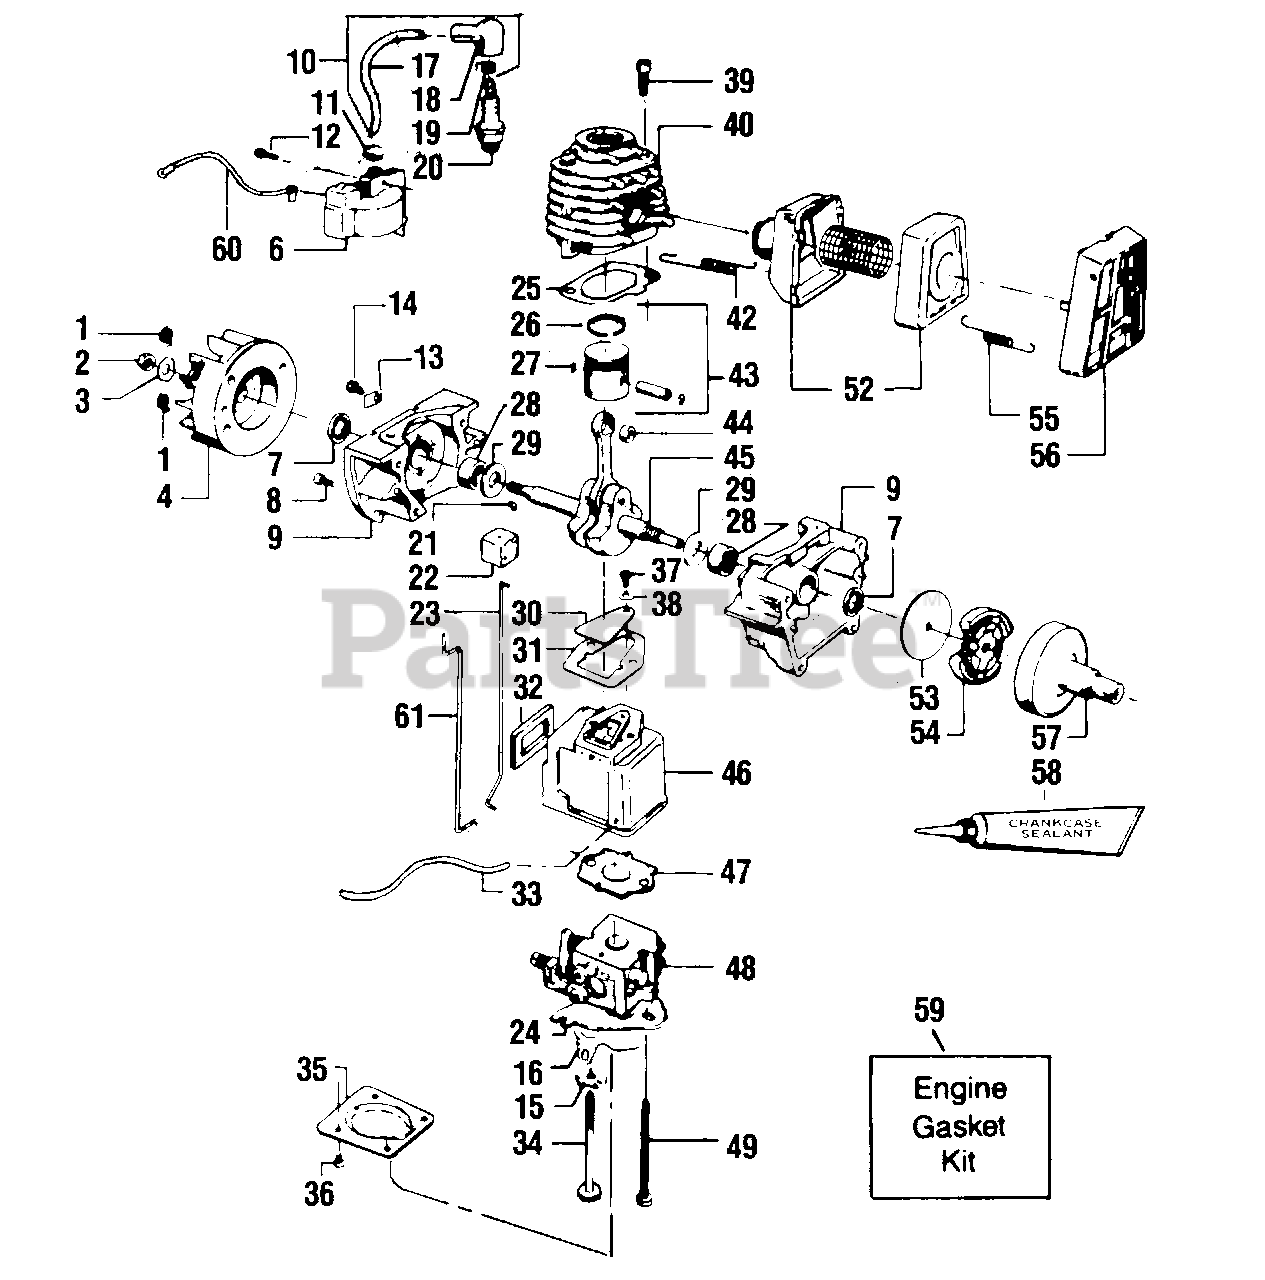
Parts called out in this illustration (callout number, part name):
1	Starter Dog Spring
2	Flywheel-Nut
3	Flywheel Washer
4	Flywheel Assembly
6	Ignition Module Kit
7	Crankcase Seal
8	Screw-Crankcase
9	Crankcase Assembly
10	High Tension-Load Assembly Incl. #17, 18 & 19
11	Grommet-Plug Wire
12	Screw #8-32x3/4"- Fil. Hd.-Ignition Module
13	Choke Wire Clamp
16	Choke Shutter
17	High Tension Lead Wire
18	Spark Plug Boot
19	Spark Plug Lead Connector
20	Spark Plug (CJ-14)
21	Key-Flywheel
22	Boot-Throttle Choke Wire
23	Throttle Wire (Red)
24	Guide Plate
25	Cylinder Gasket
26	Ring-Piston
27	Retainer-Wrist Pin
28	Bearing-Crankcase
29	Washer-Thrust-Crankcase
30	Reed Valve
31	Gasket-Carburetor Case to Crankcase
32	Seal-Carburetor Case
33	Line Kit
35	Cover-Carburetor Case
36	Screw-#6-18x9/16"-Pan Hd.-Carburetor Case Cover
37	Screw-#5-19x5/16"-Pan Hd. Reed Valve
38	Washer-Reed Valve Screw
39	Screw-#14-20x3/4" Hex Socket Hd. Cylinder
40	Cylinder
42	Spring-Muffler Detachment
43	Piston Kit
44	Bearing-Wrist Pin
45	Crankshaft & Rod Assembly
46	Carburetor Housing
47	Gasket-Carburetor
48	Carburetor
49	Screw-#10-24x1-7/8"-Fil. Hd. Carburetor
52	Muffler Ass'y.
53	Kit-Clutch Washer
54	Kit-Clutch Assembly
55	Spring-Muffler Guard
56	Guard-Muffler
57	Coupling & Bearing Assembly
58	Sealent-Crankcase (Not Supplied with Unit)
59	Kit-Engine Gasket
60	Lead Wire-Kill Switch
61	Choke Wire
